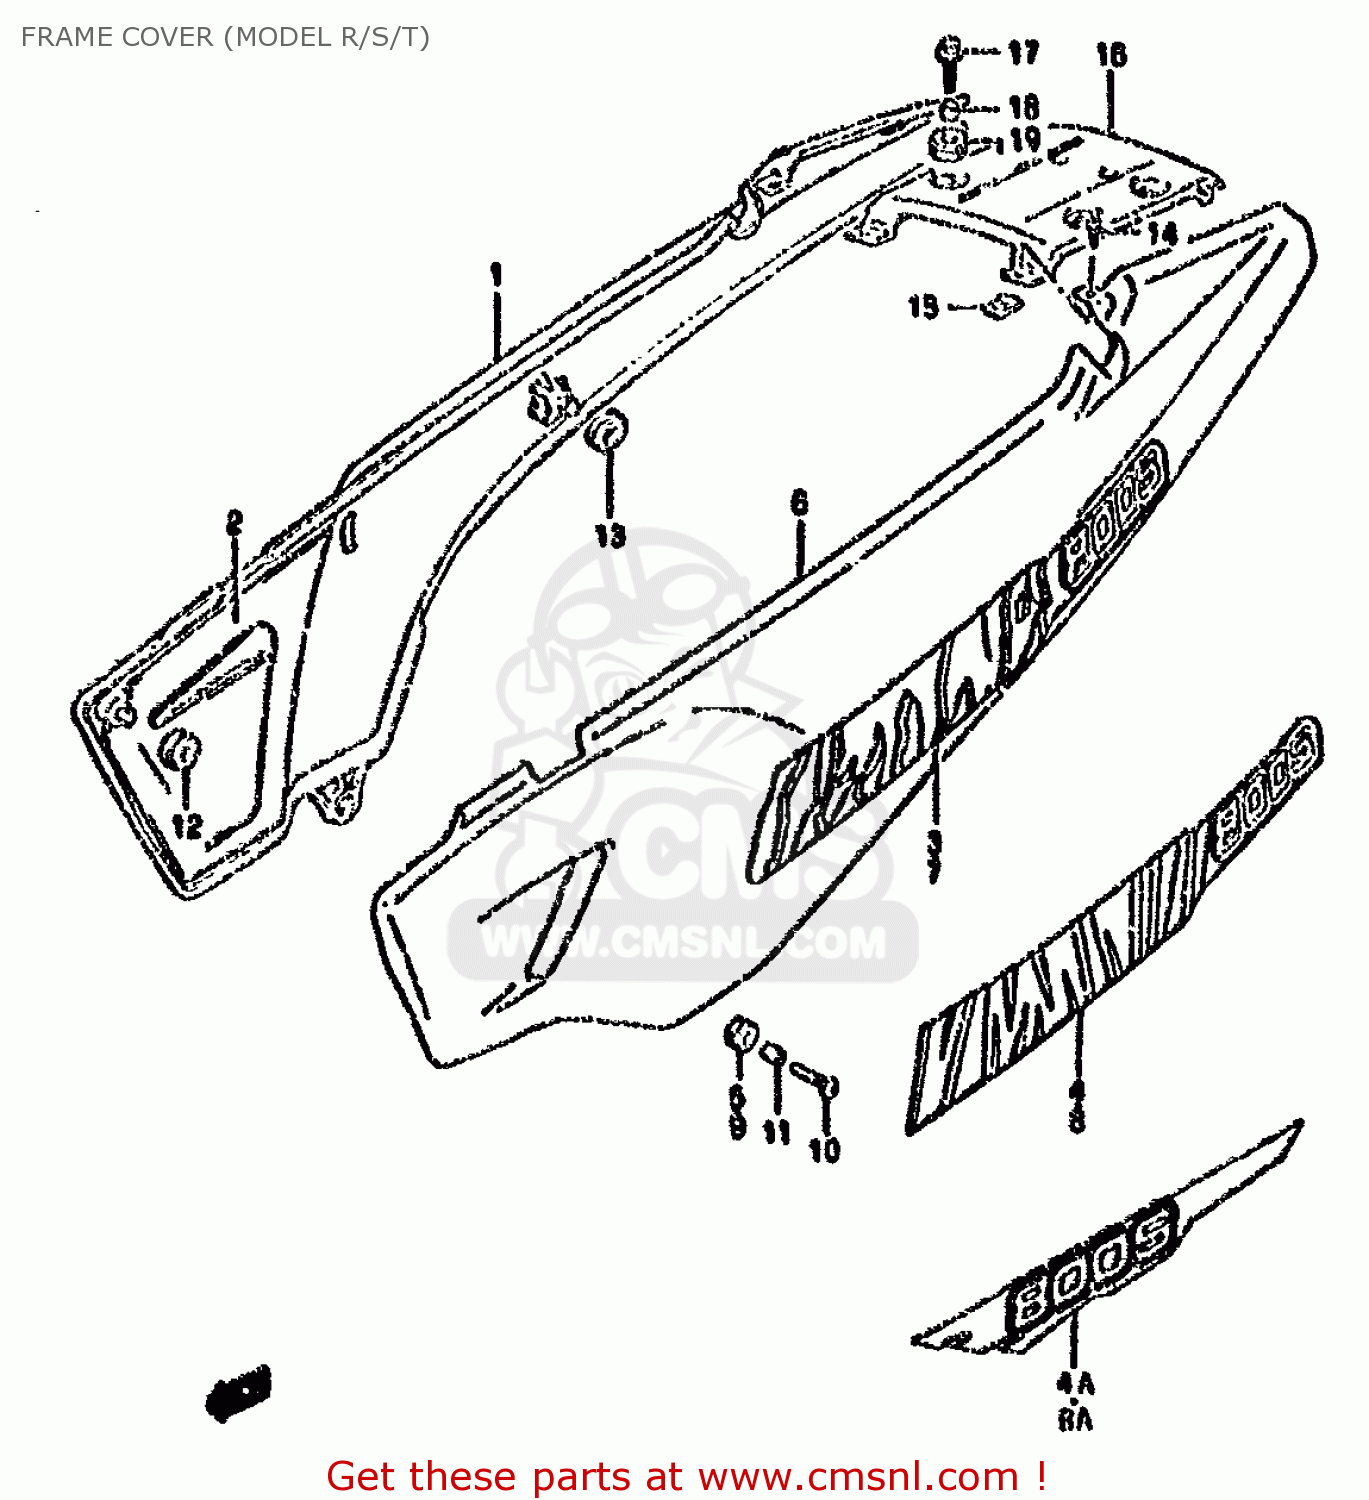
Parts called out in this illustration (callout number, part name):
1	COVER,FRAME,R(GREEN)
2	HEAT SHIELD
3	TAPE SET,RH
4	TAPE,RH
4A	TAPE,RH
5	CUSHION
6	COVER,FRAME,L(BLACK)
7	TAPE SET,LH
8	TAPE,LH
8A	TAPE,LH
9	CUSHION
10	SCREW(6X20)
11	SPACER (6.1X9X10)
12	CUSHION
13	CUSHION
14	SCREW L:12
15	NUT
16	COVER,FRAME CN
17	BOLT
18	SPACER (8.8X12X12.5)
19	CUSHION
21	CUSHION
